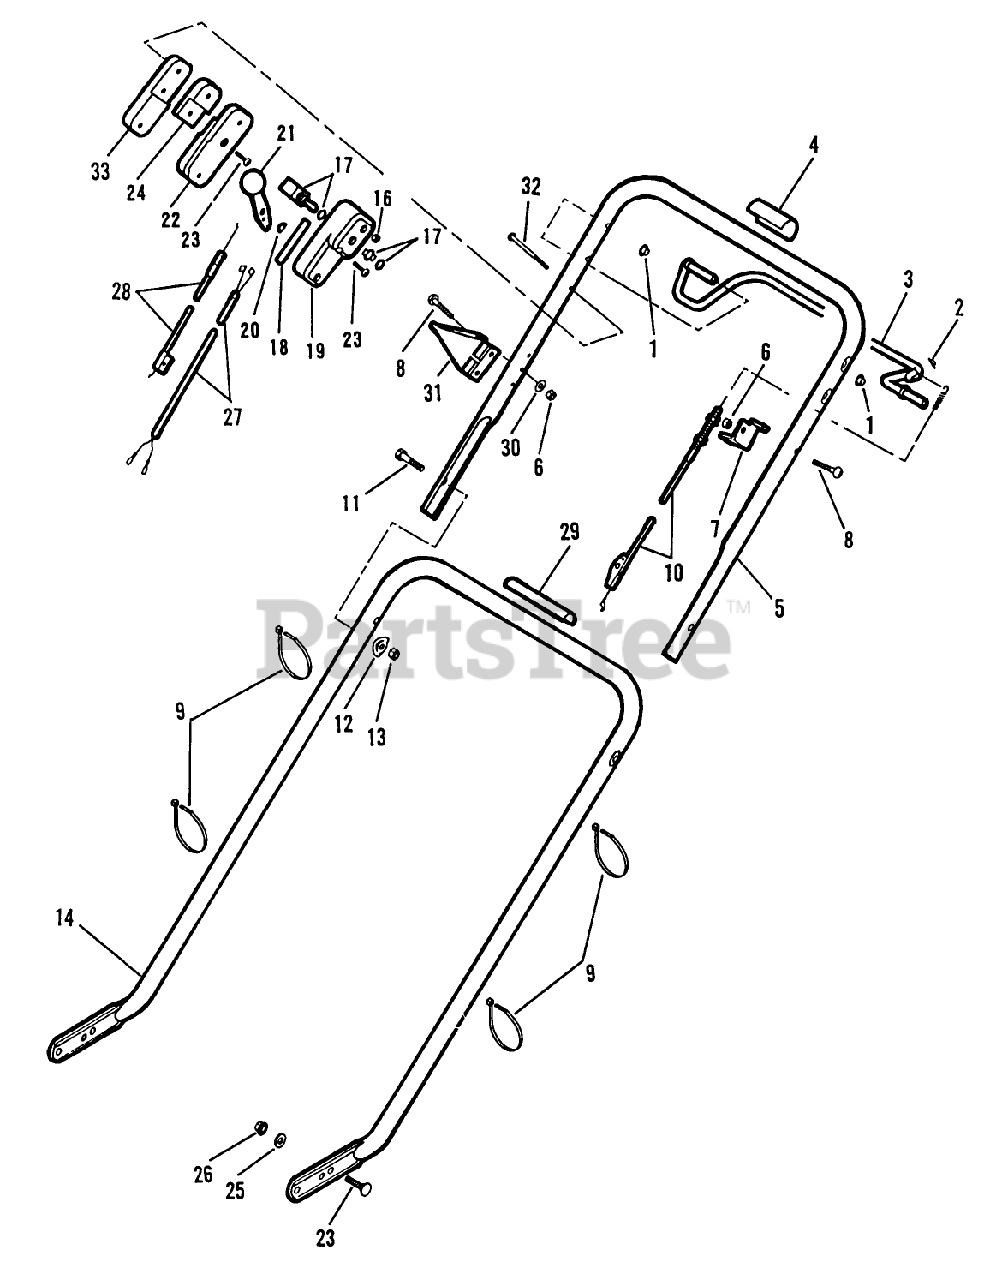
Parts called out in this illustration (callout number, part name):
6	LOCKNUT E
7	ANCHOR C'DUIT TRO
10	CABLE - CONTROL
12	WASHER-CURVED
13	NUT-LOCK F
16	NUT C/LOCK E
20	WASHER-SPRING
21	LEVER&KNOB AY WES
23	SCREW
28	CABLE TH'TTLE WES
30	WASHER
32	SCREW
33	OUTER CONTROL CASE
